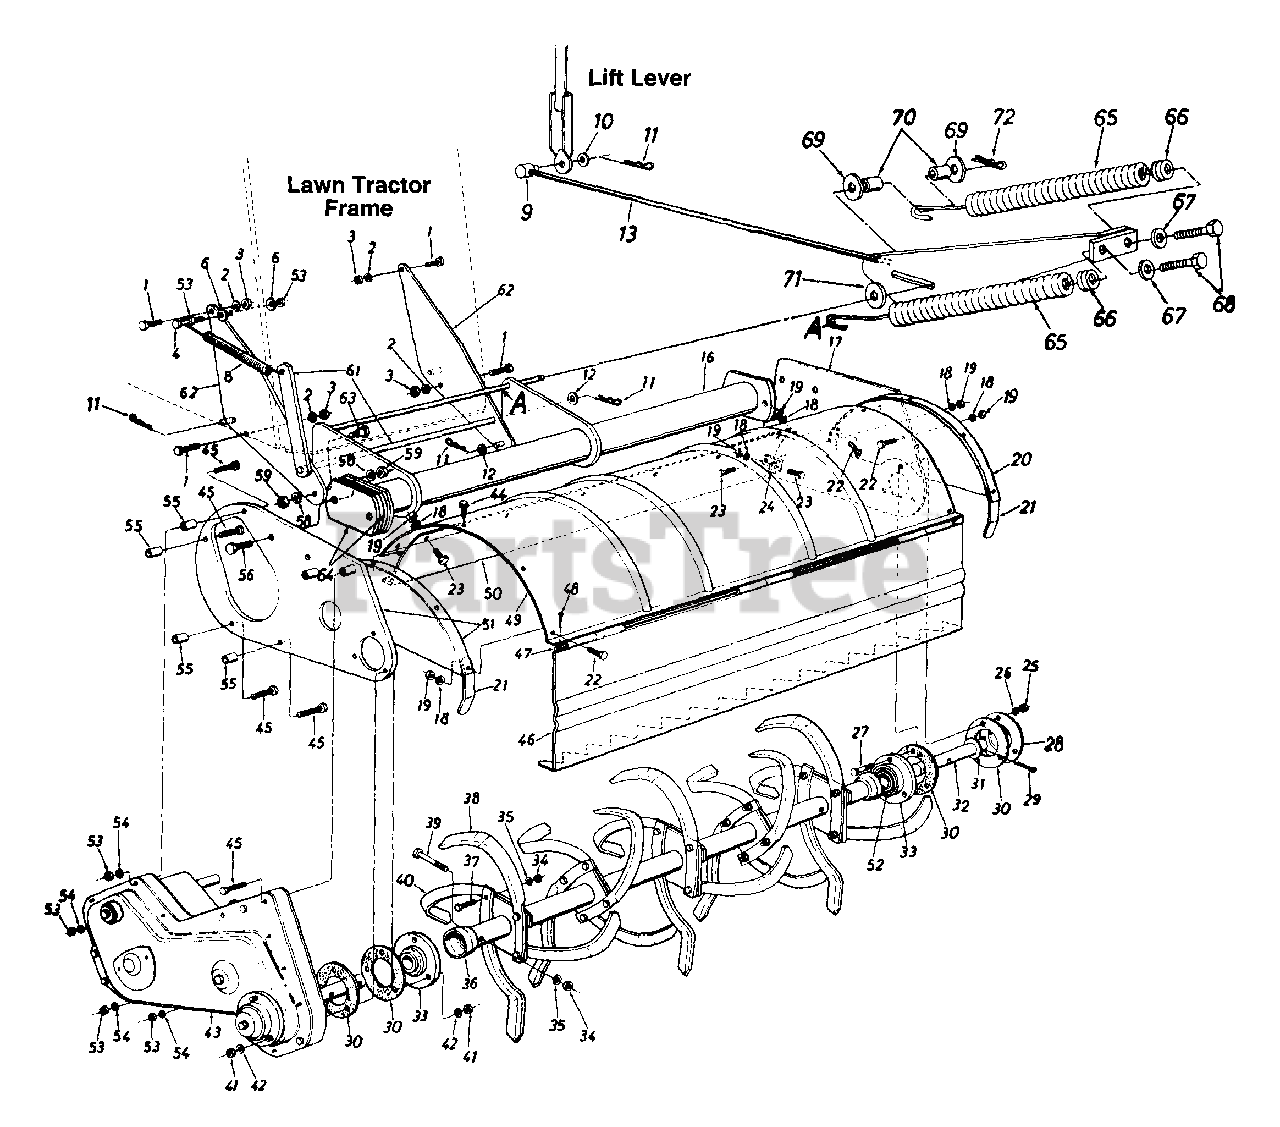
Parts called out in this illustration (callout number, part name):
1	Hex Bolt 3/8-24 x .88" Lg.
2	L-Wash. 3/8" I.D. - H.D.
3	Hex Nut 3/8-24 Thd.
4	Hex Bolt 1/4-20 x 1.25" Lg.
6	Bell-Wash. 1/4" I.D.
8	Ext. Spring 7.75" Lg.
9	Adjustment Ferrule 1/2-13 Thd.
10	Fl-Wash. .64" I.D. x 1.24" O.D. x .06"
11	Intern. Cotter Pin 1/2" Dia.
12	Fl-Wash. .51" I.D. x 1.0" O.D. x .06"
13	Lift Bracket Ass'y.
14	Comp. Spring 1.5" O.D. x 15" Lg.
15	Fl-Wash. .51" I.D. x 1.5" O.D. x .075"
16	Pivot Bracket Assembly
19	Hex Nut 5/16-24 Thd.
23	Hex Bolt 5/16-24 x .62" Lg.
24	Chute Pivot Bracket
25	Hex L-Nut 5/16-18 Thd.
27	Hex Bolt 5/16-18 x 1" Lg. (Grade 5)
30	Gasket for Brg. Housing
31	Fl-Wash. 1.25" I.D. x 2.0" O.D. x .06"
32	Tine Shaft 1.25" Dia. x 6.25" Lg.
33	Bearing Housing w/Bearing
38	Tine 14" x 5/16"
39	Hex Bolt 3/8-24 x 2.25" Lg.
40	Tine 14" x 5/16"
43	Chain Case Ass'y. Comp.
44	Hex TT-Tap Scr. 5/16-18 x .62" Lg.
45	Hex Bolt 1/4-20 x 2.75" Lg.
48	Cotter Pin 1/8" Dia. x 1" Lg.
53	Hex Nut 1/4-20 Thd.
54	L-Wash. 1/4" I.D.
55	Spacer .28" I.D. x .62" O.D. x .9" Lg.
56	Hex Bolt 1/2-20 x 1.5" Lg.
58	L-Wash. 1/2" I.D.
59	Hex Nut 1/2-20 Thd.
61	Idler Brkt. Support Arm Ass'y.
62	Pivot Brkt. Support
63	Shoulder Bolt
64	Support Plate
65	Helper Spring
66	Spring Insert
67	Fl-Wash. .34" I.D. x .68" O.D.
68	Hex Bolt 5/16-18 x 3.25" Lg.
69	Fl-Wash. .51" I.D. x 1.5" O.D.
70	Split Spacer .505" I.D. x .57" Lg.
71	Fl-Wash. .531" I.D. x 1.25" O.D.
72	Internal Cotter Pin 1/2" Dia.
